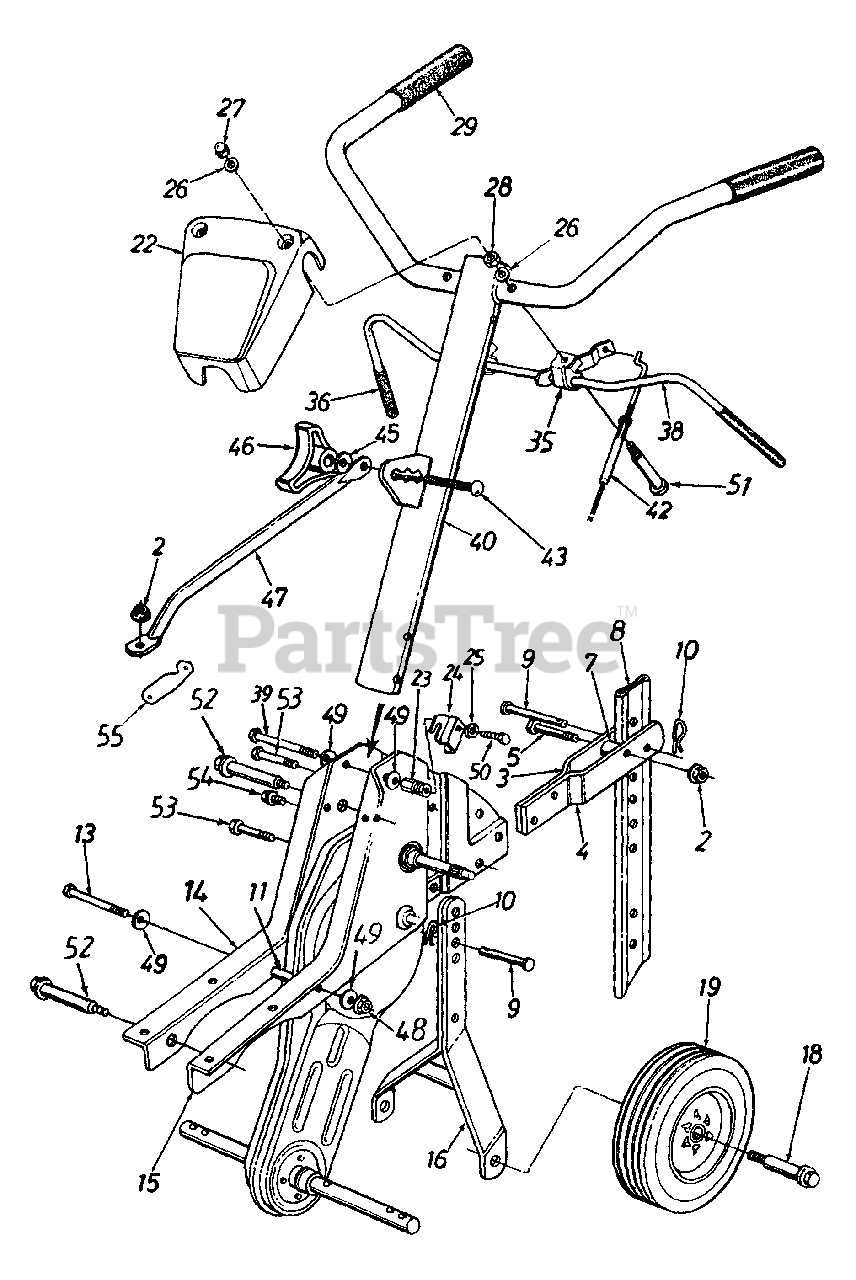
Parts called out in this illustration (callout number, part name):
2	Hex Flange L-Nut 5/16-18 Thd. (Gr. 5)
5	Hex Bolt 5/16-18 x 1.5" Lg.
7	Spacer .32" I.D. x .75" O.D.
9	Clevis Pin .375" I.D. x 1.62" Lg.
10	Internal Cotter Pin
11	Spacer .326" I.D. x .47" O.D.
13	Hex Bolt 5/16-16 x 2.75" Lg.
18	Shld. Bolt .496" Dia. x 1.45"
19	Wheel Ass'y.
22	Handle Cover
23	Spec. Hex Nut
25	L-Wash. 5/16" I.D.
26	Fl-Wash. .266" I.D. x .625" O.D.
27	Hex L-Stop Nut 1/4-20 Thd.
28	Hex Nut 1/4-20 Thd.
29	Grip - Handle
35	Clutch Handle Holder
36	Grip - Clutch
39	Hex Bolt 5/16-18 x 3" Lg.
43	Carr. Bolt 5/16-18 x 1" Lg.
45	Wash. Bell. .340" ID x .872" OD
46	Hand Knob
49	Bell-Wash. .345" I.D. x .88" O.D.
50	Hex Bolt 5/16-18 x .75" Lg
51	Hex Bolt 1/4-20 x 2.25" Lg.
52	Shld. Bolt
53	Hex Wash. Hd. TT-Tap Scr. 5/16-18 x .62"
54	Hex Wash. Hd. TT-Tap Scr. 5/16-16 x 1"
55	Engine Brkt.
